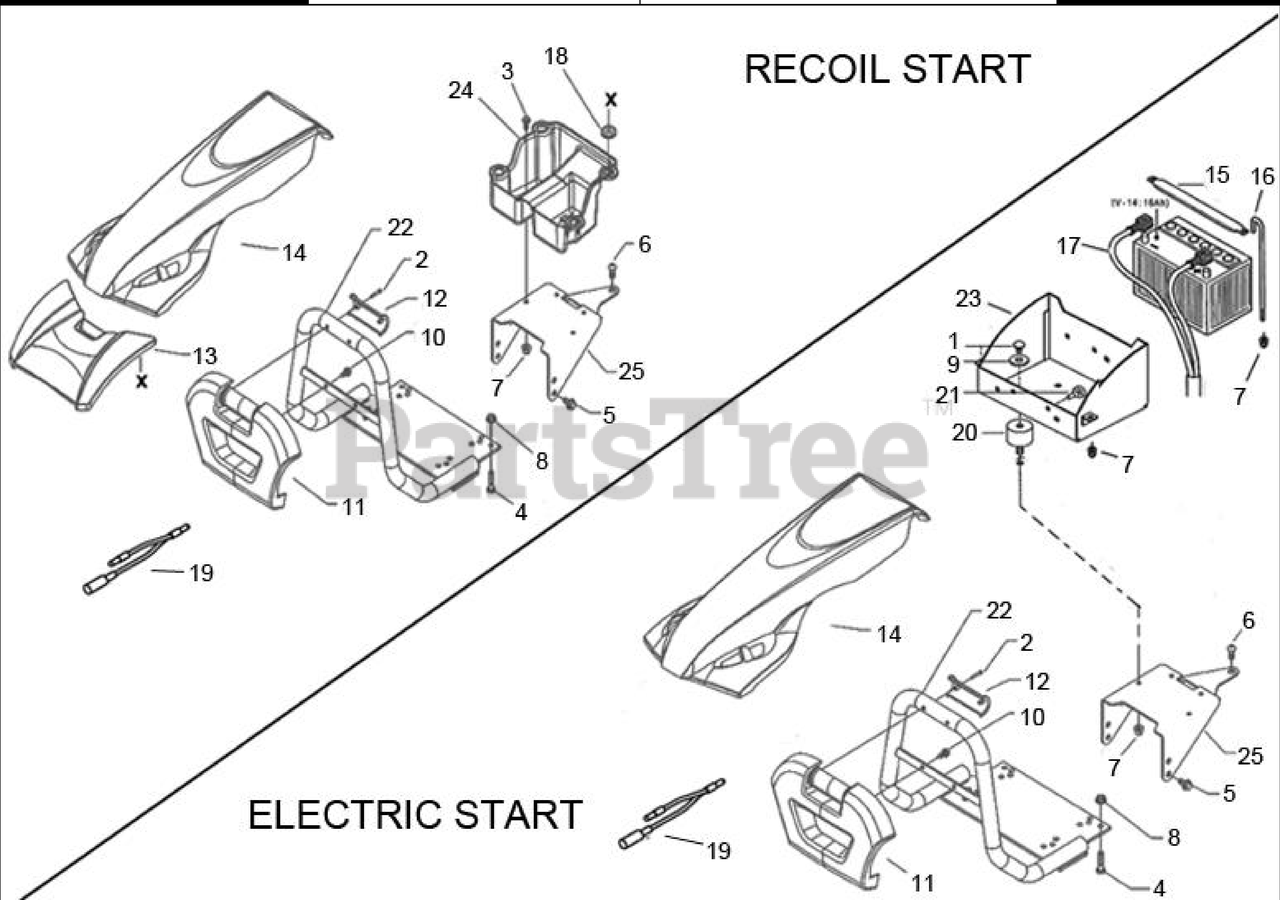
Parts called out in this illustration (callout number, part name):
1	CARRIAGE BOLT M6X24
2	SCREW 3.5X25
3	SCREW TE C/F M6X20 DIN 6921 8G
4	SCREW TE M8X40 UNI 5739 8G
5	SCREW TE C/F M8X16 DIN 6921
6	SCREW TBCEI M10X16 ISO 7380
7	SELFLOCK M6 FL NY DIN 6926
8	SELFLOCK NUT M8 6S
9	WASHER FLAT M9X24
10	RIBBED SCREW 6.3X19 UNI 6950
11	FRONT BUMPER COVER
12	CLAMP FOR FRONT BUMPER COVER
13	LOWER COVER (Not used on Electric Start Model)
14	STEERING COLUMN COVER
15	BATTERY BRACKET
16	ROD, BATTERY
17	BATTERY CABLES (ELECTRIC START)
18	SUPPORT CAP
19	WIRING HARNESS
20	SHOCK MOUNT
21	RUBBER CUSHION
22	BUMPER GX390
23	BATTERY TRAY (ELECTRIC START)
24	SUPPORT TRAY FOR LOWER COVER
25	SUPPORT BRACKET
